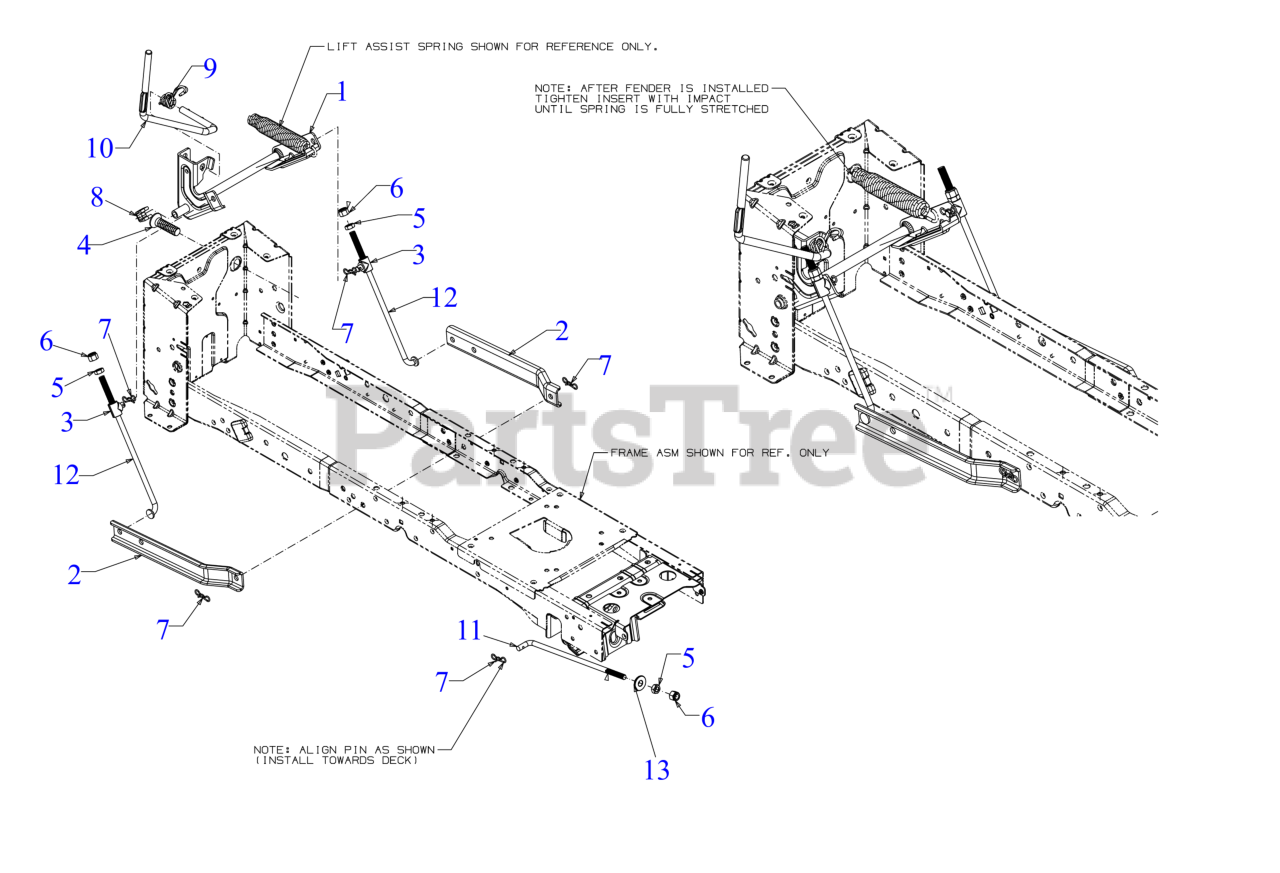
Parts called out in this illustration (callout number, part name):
1	LIFT SHAFT ASSEMBLY
2	LIFT LINK
3	LIFT ROD FERRULE
4	LIFT SPRING INSERT
6	HEX LOCK NUT NYLON
7	BOW TIE COTTER PIN
8	SPACER-LIFT SHAFT
9	TORSION SPRING
10	DECK LIFT HANDLE
11	DECK FRONT LIFT ROD
12	ADJUSTMENT LIFT ROD
13	DECK LIFT PIVOT CUP
